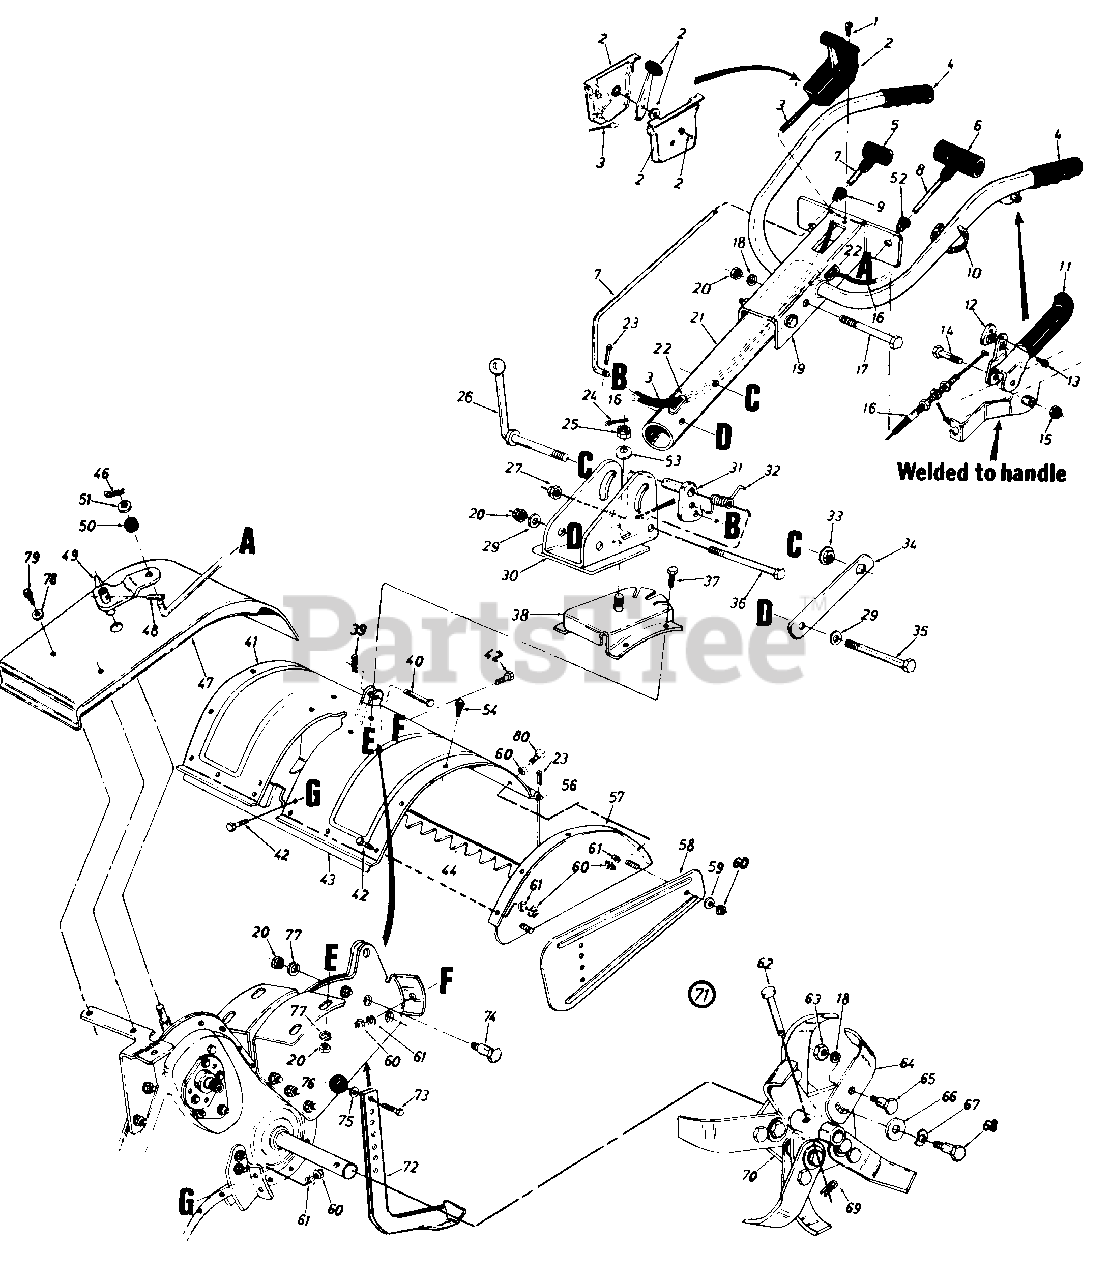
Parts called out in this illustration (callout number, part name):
1	Truss Mach. AB-Tap. Scr. #10 x .50" Lg.
2	Throttle Control Box Ass'y.
3	ThroKle Control Wire
4	Handle Grip
5	Small "T" Knob
6	Large"T" Knob
7	Clutch Rod
8	Control Rod 37" Lg.
9	Snap On Bushing 3/8" Dia.
10	Cable Tie-Self Clinching
12	Barrel Cable Hold Down
13	Hex B-Tap Scr. #10 x .44" Lg.
14	Hex Bolt 3/8-16 x 2.0" Lg.
15	Hex Cent. L-Nut 3/8-16 Thd.
16	Clutch Control Cable 53" Lg.
17	Hex Bolt 3/8-16 x 3.00" Lg.
18	L-Wash. 3/8" I.D. H.D.
19	Handle Ass'y.
20	Hex Nut 3/8-16 Thd.
23	Cotter Pin 3/32" Dia. x .75" Lg.
24	Cotter Pin 3/32" Dia. x 1.25"
25	Hex Slotted Nut 5/8-18 Thd.
26	Handle Adj. Crank
27	Hex Cent. L-Nut 3/8-16 Thd.
29	Bell-Wash. .4" I.D. x.87" O.D.
30	Handle Pivot Bracket
31	Positioner Crank Ass'y.
32	Spring Handle Adj.
33	Hex Flange Nut 3/8-24 Thd.
34	Bracket Hex Nut Retainer
35	Hex Bolt 3/8-16 x 3.25" Lg.
36	Hex Bolt 3/8-16 x 3.00" Lg. Gr. 8
37	Hex Bolt 3/8-16 x .75" Lg.
40	Clevis Pin .375" Dia.
43	Bracket Reinforcement 18"
46	Intern. Cotter Pin 5/16" Dia.
49	Shifting Crank Ass'y.
50	Rubber Washer .33" I.D.
51	Fl-Wash. .4" I.D. x 1.25" O.D.
52	Snap On Bushing 1/2" Dia.
53	Bell-Wash. .63" I.D. x 1.25"
54	Hex Wash. Tap Scr.
56	Tiller Flap Rod
60	Hex Nut 5/16-18 Thd.
61	L-Wash. 5/16" I.D.
62	Clevis Pin .375" Dia.
63	Hex Nut 3/8-24 Thd.
65	Shld. Bolt 1/2" Dia. x .175
66	Fl-Wash. .51" I.D. x 1.50"
67	Bell-Wash. .515" I.D. x 1.14"
68	Shld. Bolt 1/2" Dia. x .320
69	Intern. Cotter Pin
73	Hex Bolt 3/8-16 x .75" Lg.
74	Shld. Bolt 1/2" I.D. x .62" Lg.
75	Fl-Wash. 3/8" I.D. x 5/8" O.D.
76	Ball Knob
77	L-Wash. 3/8" I.D.
78	Fl-Wash. .281" I.D. x .62"
79	Hex Wash. Self-Tap Scr. 1/4-20 x .50" Lg.
80	Hex Bolt 5/16-18 x 1-1/4" Lg.
